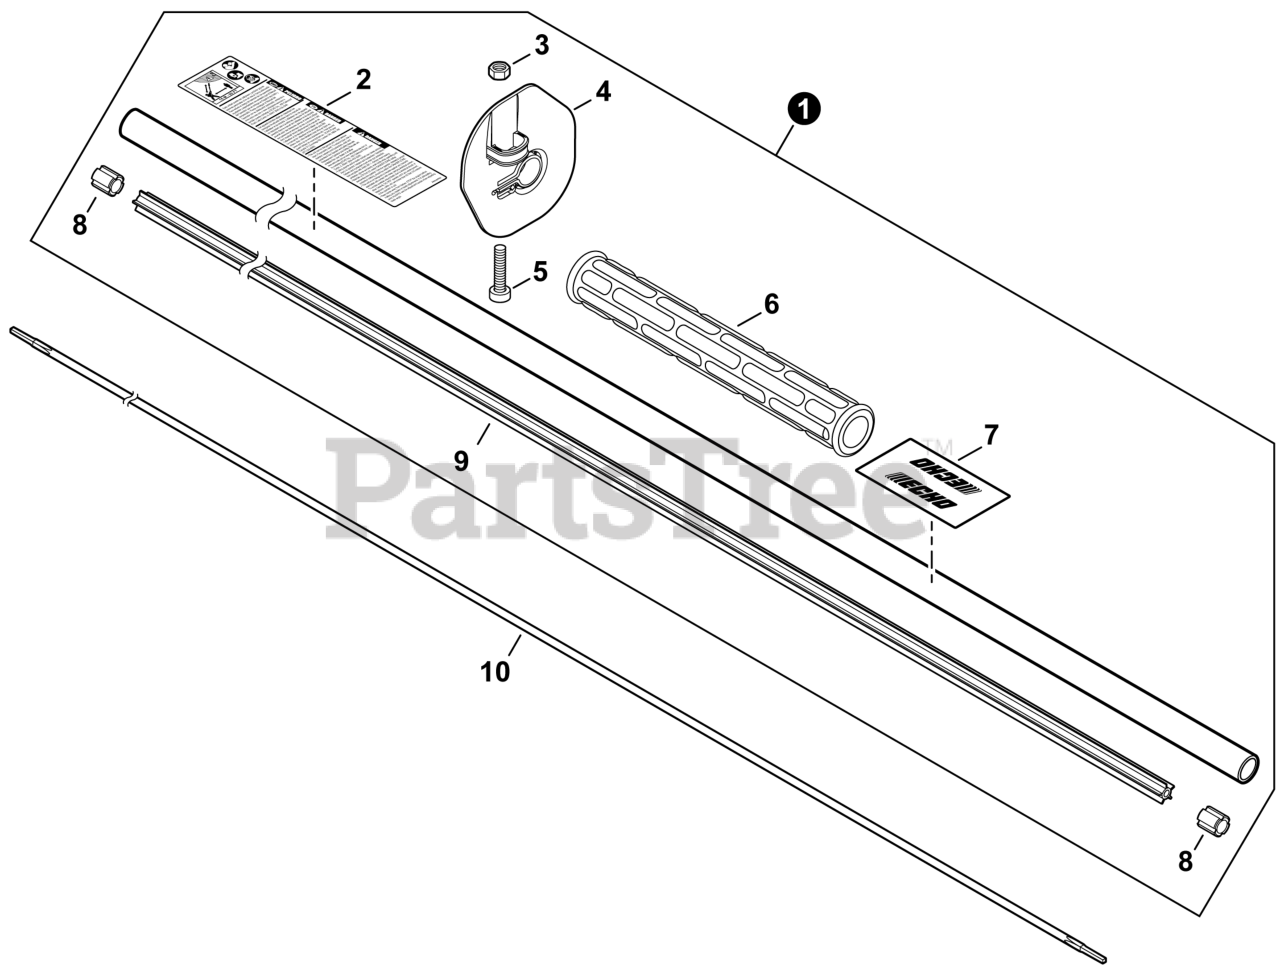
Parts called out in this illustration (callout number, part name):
1	MAIN PIPE ASSY
2	LABEL - CAUTION
4	GUARD, HAND
5	BOLT, TORX 5x20
6	GRIP, FRONT
7	LABEL - HANDLE LOCATION
9	LINER, FLEXIBLE 21.6x1420
10	DRIVESHAFT - FLEXIBLE
